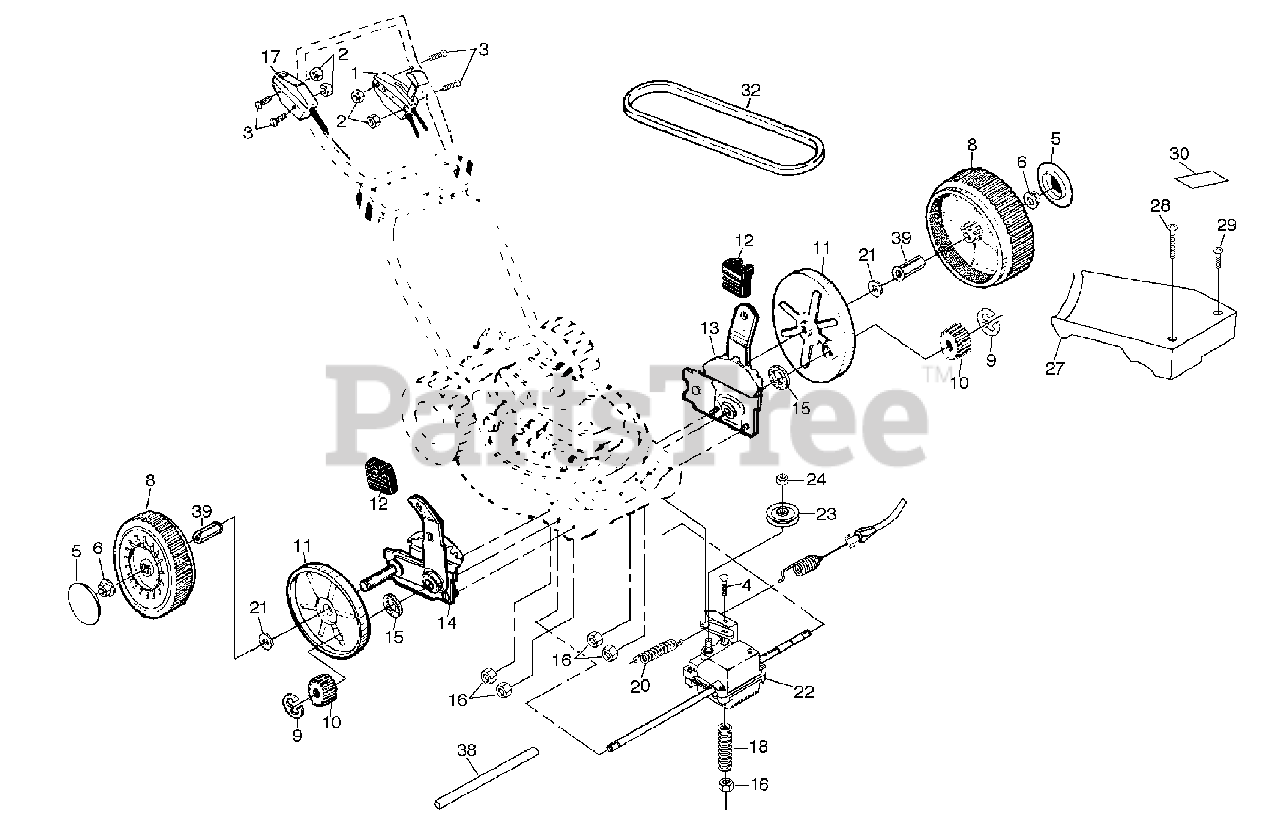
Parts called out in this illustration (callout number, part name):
1	Drive Control
2	Locknut 1/4-20
3	Hex Washer Head Screw 1/4-20 x 2-1/8
4	Carriage Bolt 1/4-20 x 2
6	Flanged Locknut
8	Wheel & Tire Assembly
11	Dust Cover
12	Selector Knob
13	Wheel Adjuster Assembly (Left)
14	Wheel Adjuster Assembly (Right)
15	Felt Washer
16	Locknut 1/4-20
17	Engine Zone Control Cable
22	Gear Case Assembly
23	Drive Pulley
24	Locknut
27	Drive Cover
28	Pan Head Machine Screw #10-24 x 2-3/4
29	Pan Head Machine Screw #10-24 x 1-3/4
30	Drive Cover Decal
32	V-Belt
38	Drive Shaft Cover
39	Wheel Bushing
